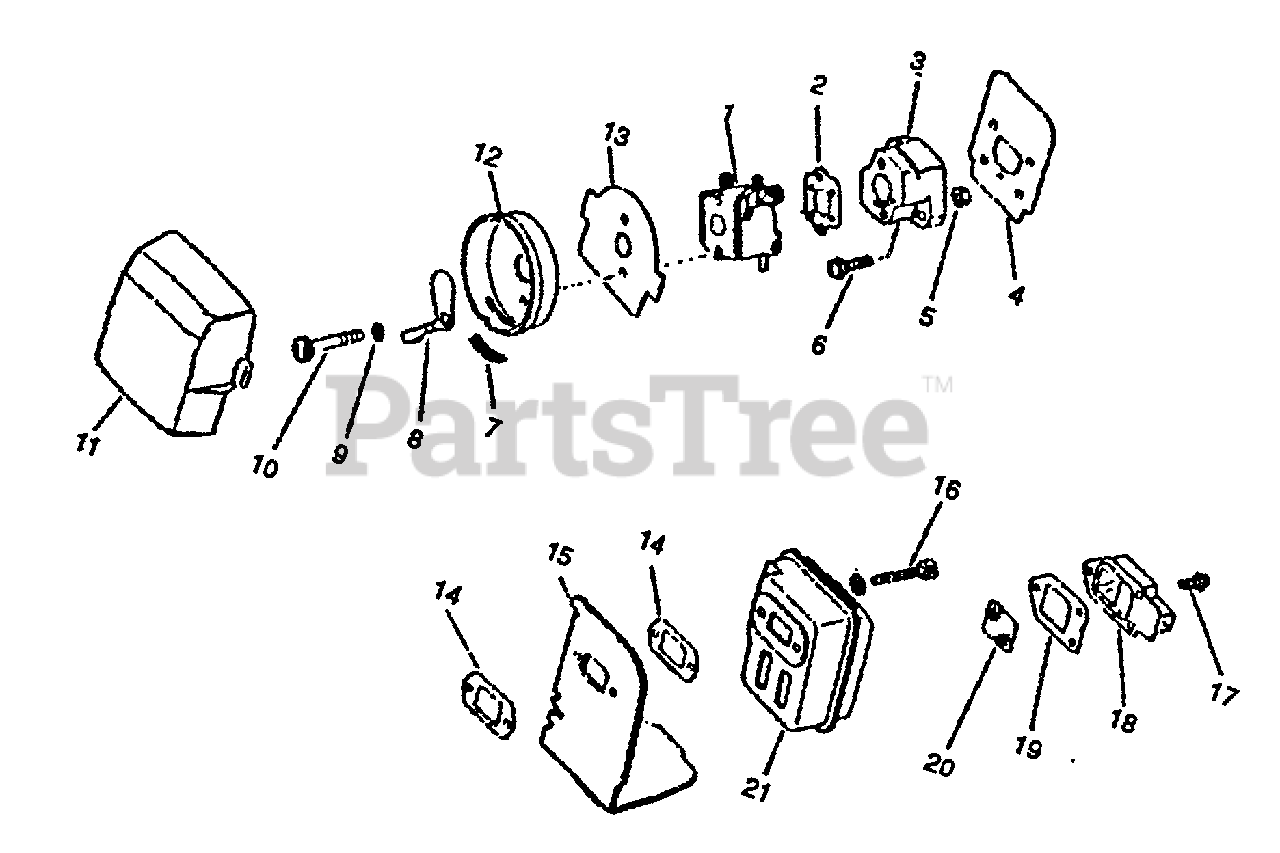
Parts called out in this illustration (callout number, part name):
1	Carburetor Asy
2	Gasket, Intake
3	Insulator
4	Gasket, Intake
6	Screw 5X20
7	Grommet
8	Shutter, Choke
10	Screw 5X57
11	Filter, Air
12	Case, Air Filter
13	Fixture, Air Cleaner
14	Gasket, Muffler
15	Cover, Muffler
16	Bolt, H.S. 5X55
17	Screw 4X10
18	Holder, Screen
19	Gasket, Muffler Lid
20	Screen, Muffler
22	Washer 5
